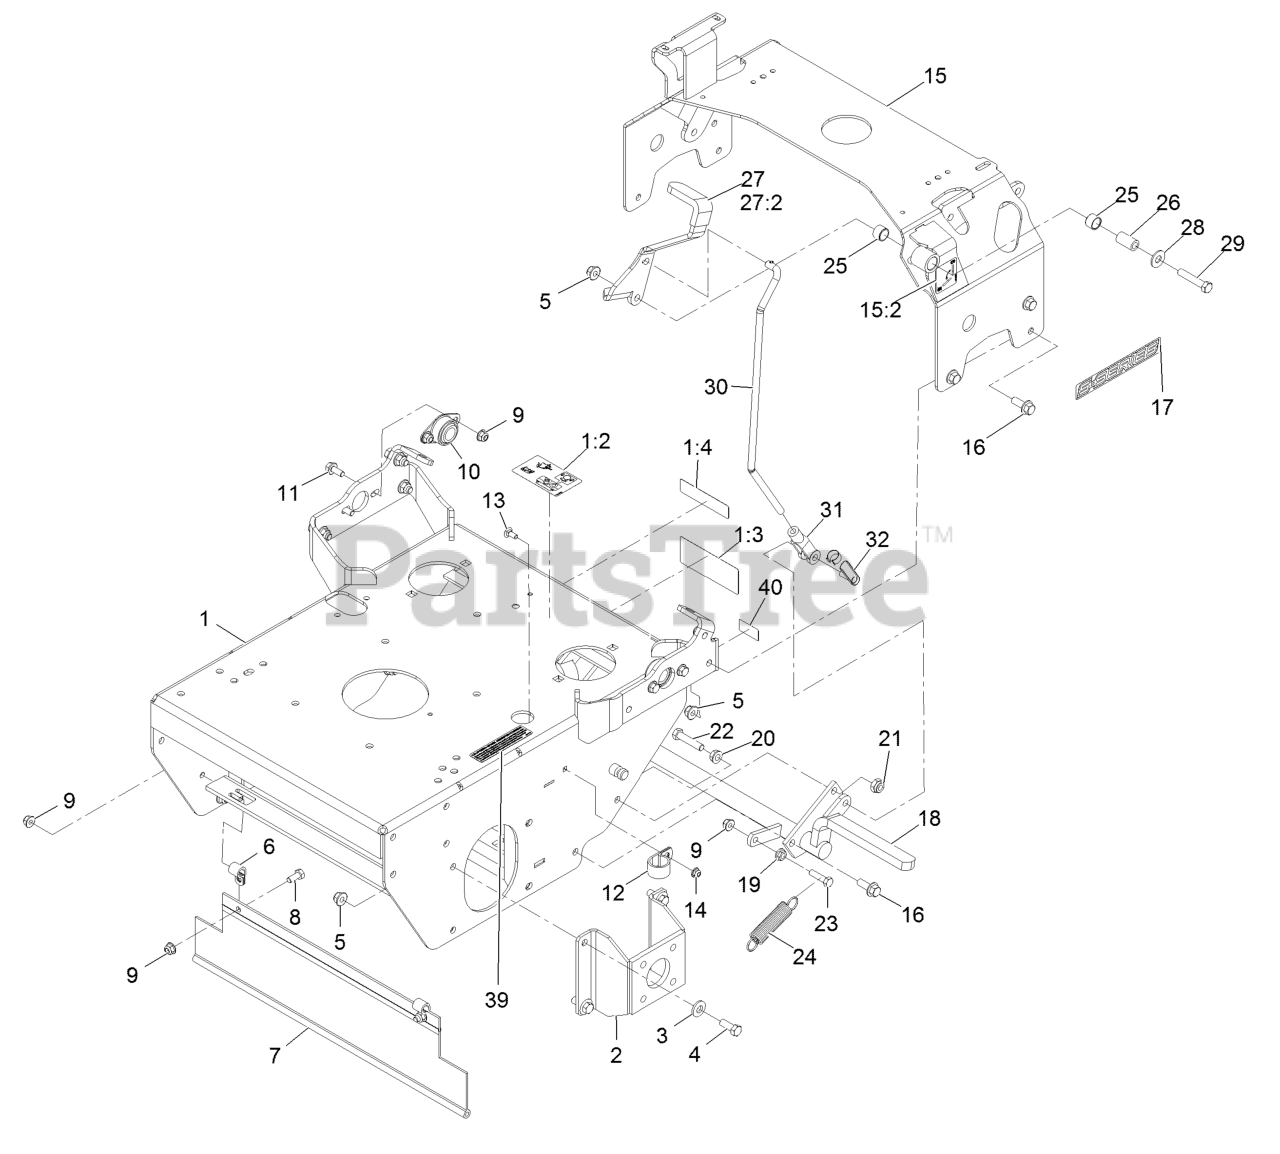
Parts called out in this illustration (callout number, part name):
1	ASM, Engine Deck W/Decals
1:2	Decal-Drive Release
1:3	Decal-Warning, Sulky
1:4	Decal-Warning
2	Mount-Wheel Motor
3	Washer-Spring Disc 3/8
4	Screw-HH 3/8-16 X 1
5	Nut-Nyloc 3/8-16 Flg
6	Clip-Loom
7	Shield-Drag
8	Screw-HH 5/16-18 X 3/4
9	Nut-Nyloc 5/16-18 Flg
10	Bearing-Flanged
11	Screw-HH Flg 5/16-18 X 3/4
12	Clip-Loom
13	Bolt-Carriage 1/4-20 X 5/8
14	Nut-Nyloc 1/4-20 Flg
15	ASM, Tank Support W/Decal
15:2	Decal-Park Brake, CE
16	Screw HHF 3/8-16 X 1
17	Decal-S-Series
19	Nut-Whizlock 5/16-18
20	Nut-Whizlock 3/8-16
21	Nut-Lock, NI
22	Screw-HH 3/8-16 X 1 3/4
23	Screw-HH 5/16-18 X 1 1/4
25	Sleeve-Bushing
26	Bushing-Pivot
27	ASM, Brake Lever W/ Grip
27:2	Grip-Lever
28	Washer-3/8 Std
29	Screw-HH 3/8-16 X 2
30	Linkage, Brake
31	Yoke-Linkage, Brake
32	Pin-Clevis Spring 3/8
39	Decal-Arrester, Spark
40	Decal-Patent
